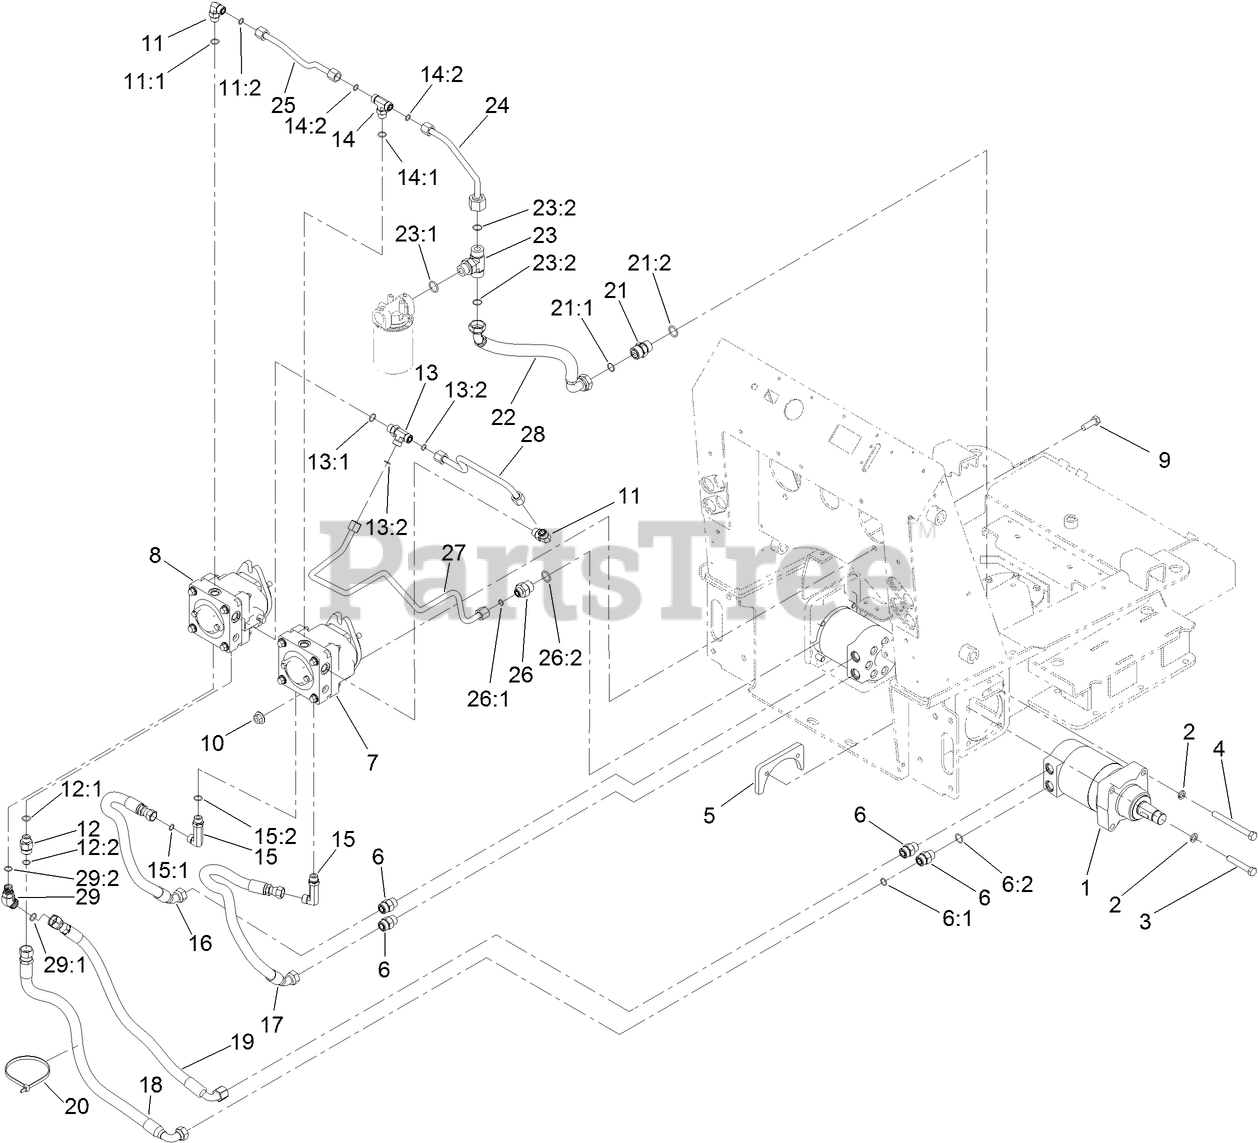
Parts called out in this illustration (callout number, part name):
1	HYD MOTOR ASM
2	WASHER-LOCK
3	SCREW-HH, TAP
4	SCREW-HH
5	PLATE-MOUNTING
6	FITTING-STRAIGHT
6:1	O-RING
6:2	O-RING
7	PUMP-HYD, RH
8	PUMP-HYD, LH
9	SCREW-HH
10	NUT-LOCK, FLANGE
11	FITTING-ELBOW, 90 DEG
11:1	O-RING
11:2	O-RING
12	FITTING-STRAIGHT
12:1	O-RING
12:2	O-RING
13	FITTING-TEE
13:1	O-RING
13:2	O-RING
14	FITTING-HYD, TEE
14:1	O-RING
14:2	O-RING
15	FITTING-ELBOW 90 LONG
15:1	O-RING
15:2	O-RING
16	HOSE-HYD
17	HOSE-HYD
18	HOSE-HYD
19	HOSE-HYD
20	TIE-CABLE
21	VALVE-CHECK, HYD
21:1	O-RING
21:2	O-RING
22	HOSE-HYD
23	FITTING-TEE
23:1	O-RING
23:2	O-RING
24	TUBE-HYD
25	TUBE-HYD
26	FITTING-STR
26:1	O-RING
26:2	O-RING
27	TUBE-HYD
28	TUBE-HYD
29	FITTING-HYD, 45 DEG
29:1	O-RING
29:2	O-RING
